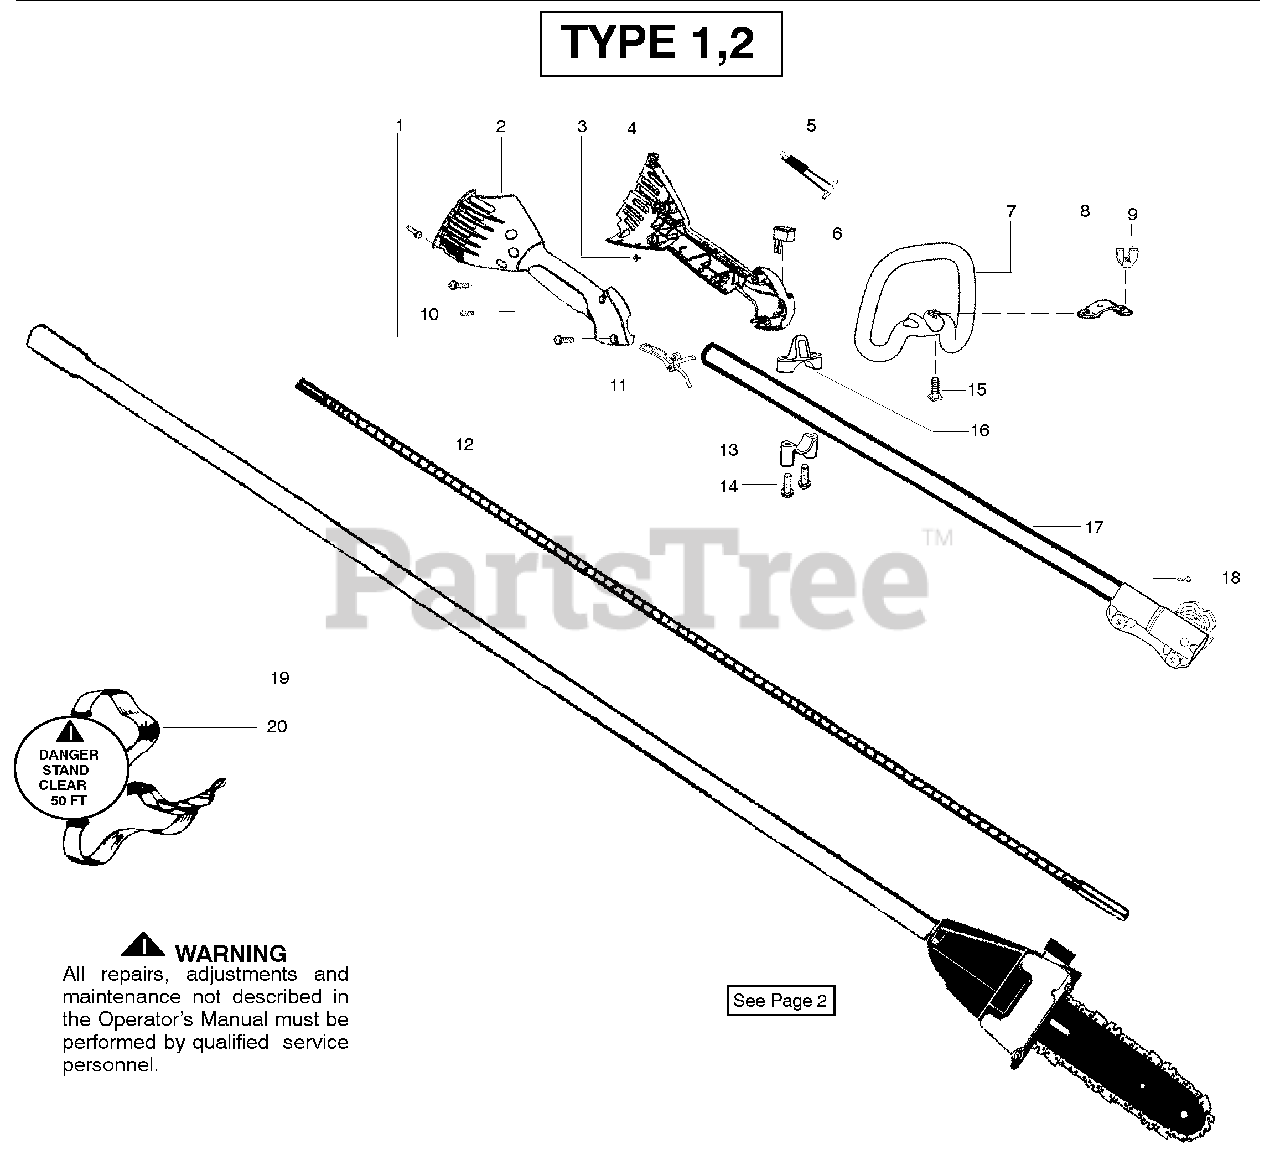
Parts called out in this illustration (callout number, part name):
2	Hsg.-Throttle right
3	Screw-Cable Ret.
4	Hsg.-Throttle left
7	Assy-Handle
9	Wingnut
10	Screw-Align
11	Trigger-Throttle
17	Kit-Upper Shaft
19	Assy-Driveshaft
20	Assy-Shoulder Strap
